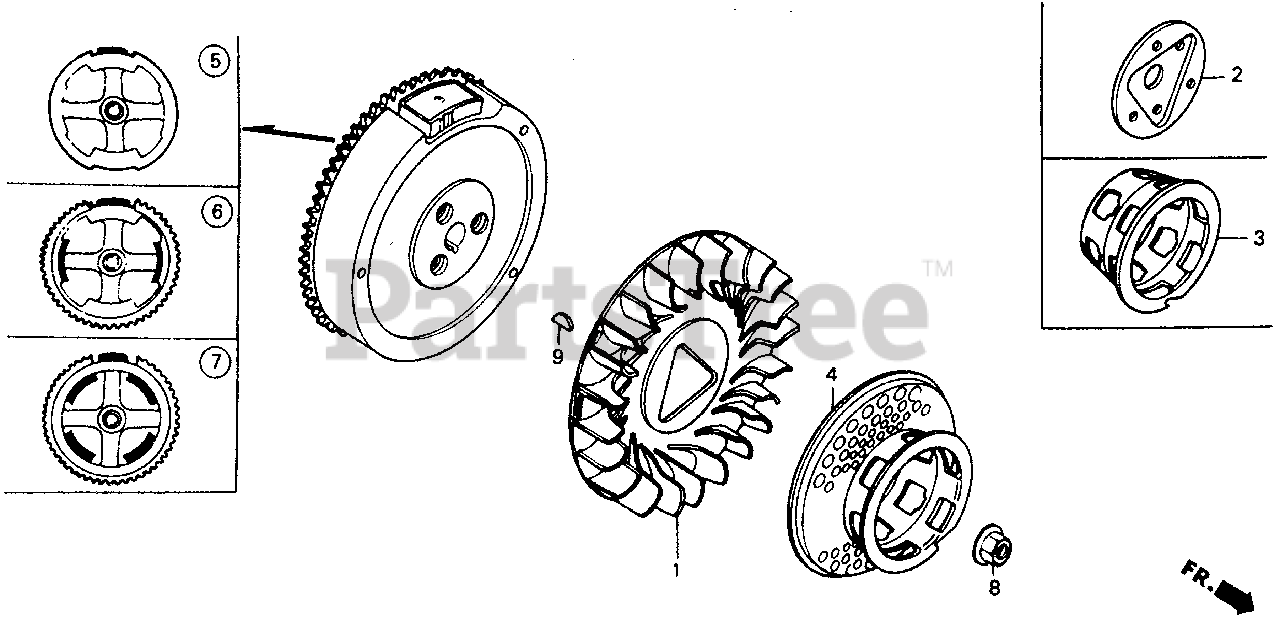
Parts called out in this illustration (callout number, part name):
1	FAN, COOLING
4	PULLEY, STARTER (SCREEN GRID)
5	FLYWHEEL
8	NUT, SPECIAL (16MM)
9	KEY, SPECIAL WOODRUFF (25X18)
